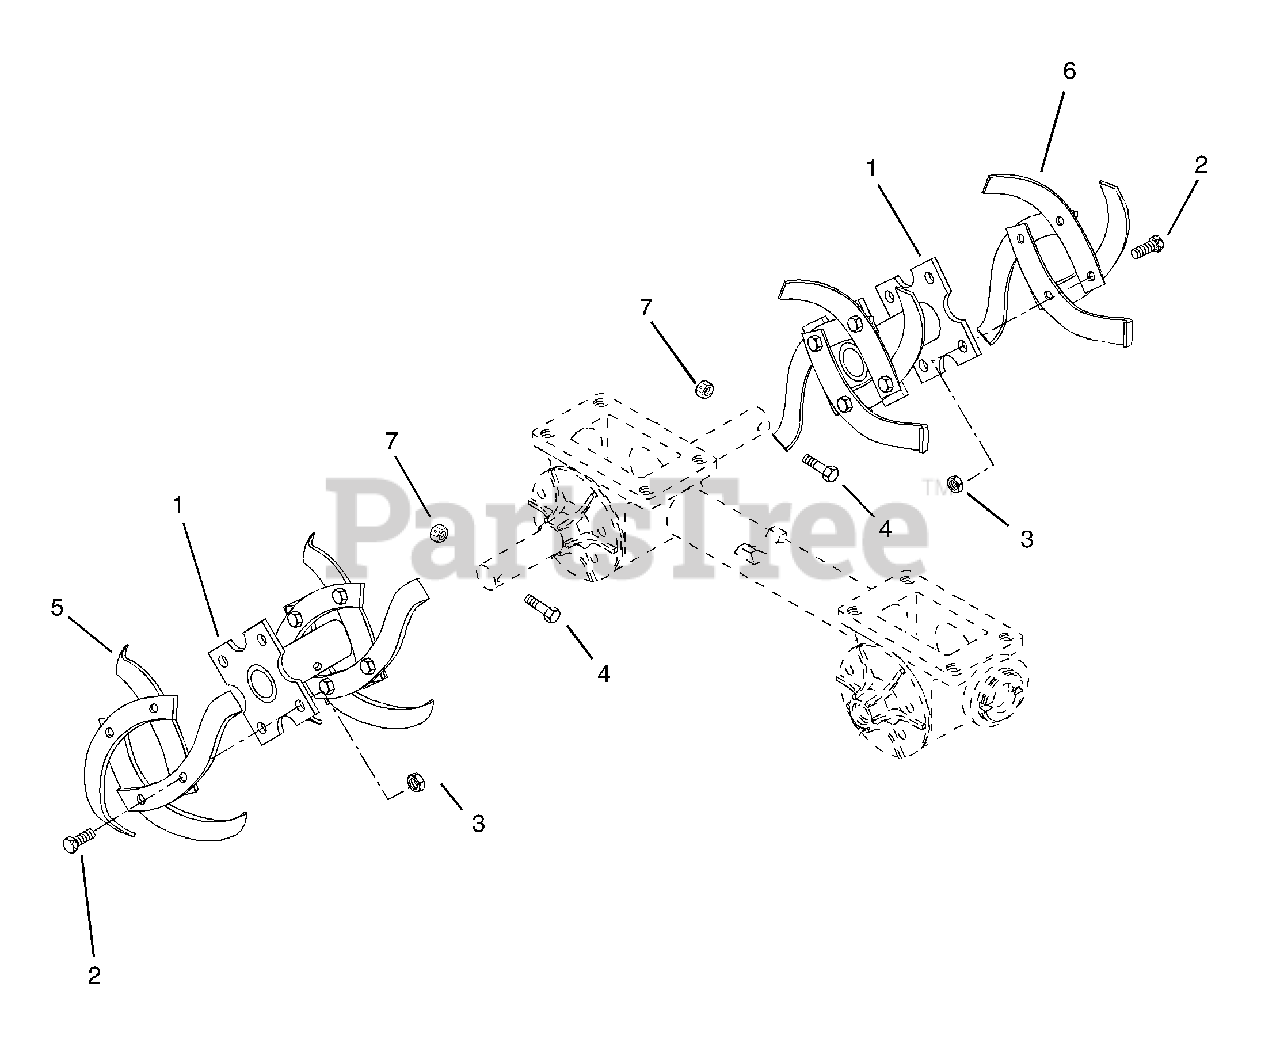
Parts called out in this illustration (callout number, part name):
1	HOLDER - BOLO TINE
2	@BLT-HEX .38-16X1.00 GR5 YWZC
3	@NUT-LK-CTR-JAM .375-16 YWZC
4	@BLT-HEX .38-16X1.75 GR5 YWZC
5	RH BOLO TINE
6	LH BOLO TINE
7	@NUT-LK-CTR .38-16 YWZC
